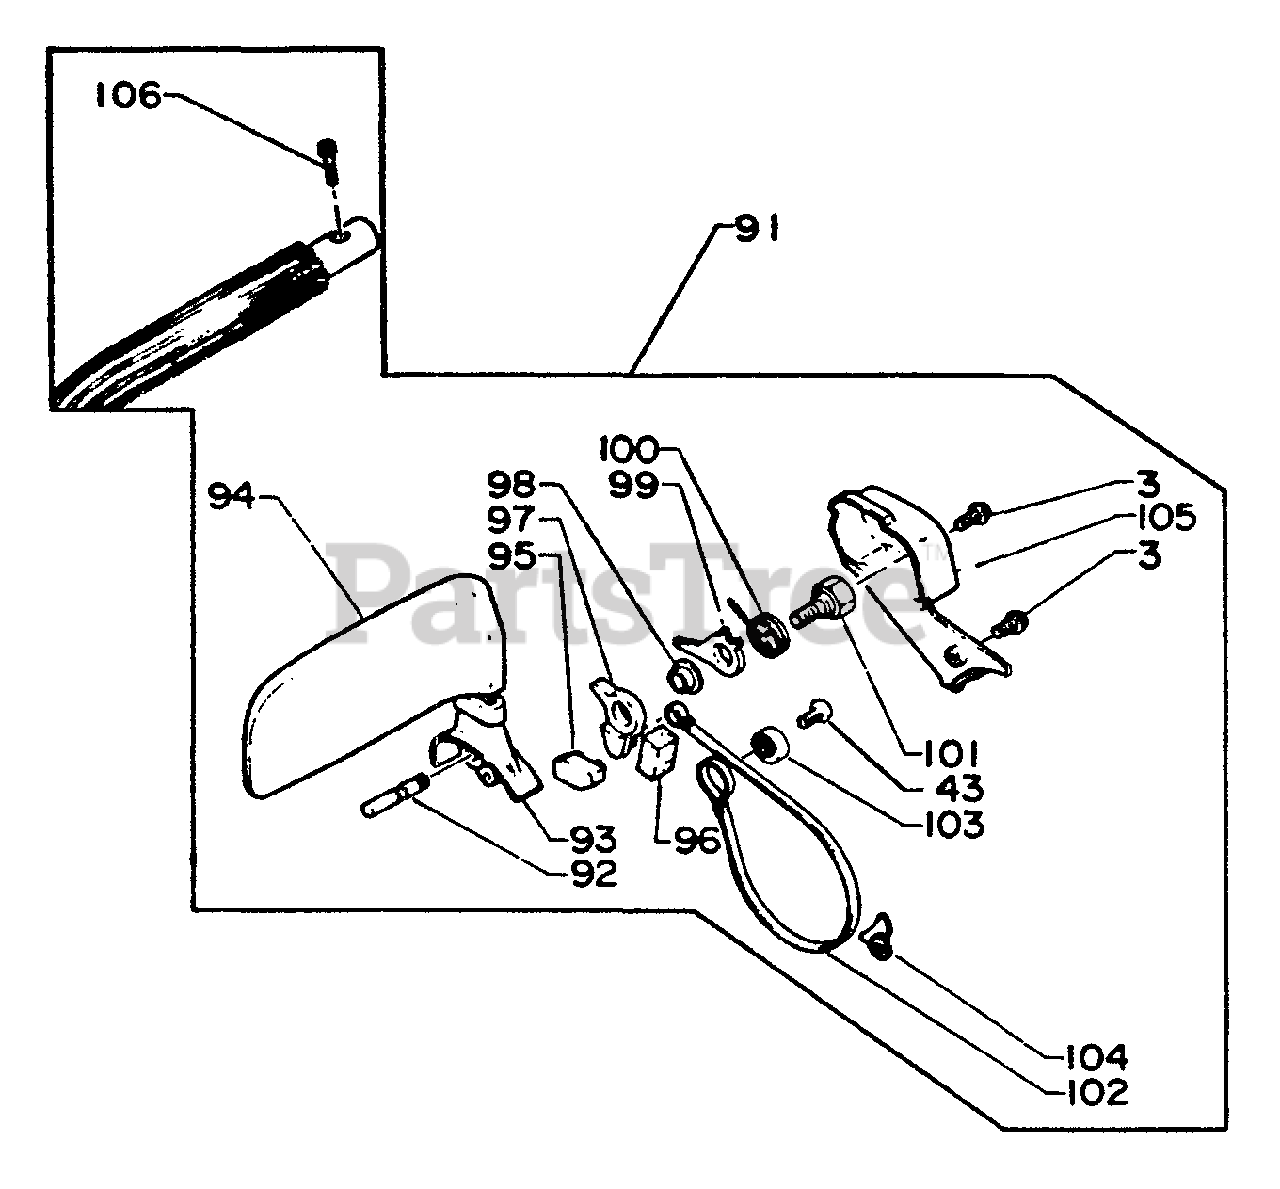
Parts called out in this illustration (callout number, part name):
3	SCREW 4×12
43	SCREW 5×10
91	CHAIN BRAKE ASSY
93	COVER, BRAKE
94	LEVER, BRAKE
95	RESET, BRAKE
96	SEAL
97	CONNECTOR
100	SPRING, RETURN
102	BAND, BRAKE
103	ADJUSTER, BRAKE BAND
104	RETAINER, BRAKE BAND
106	BOLT 5×25
